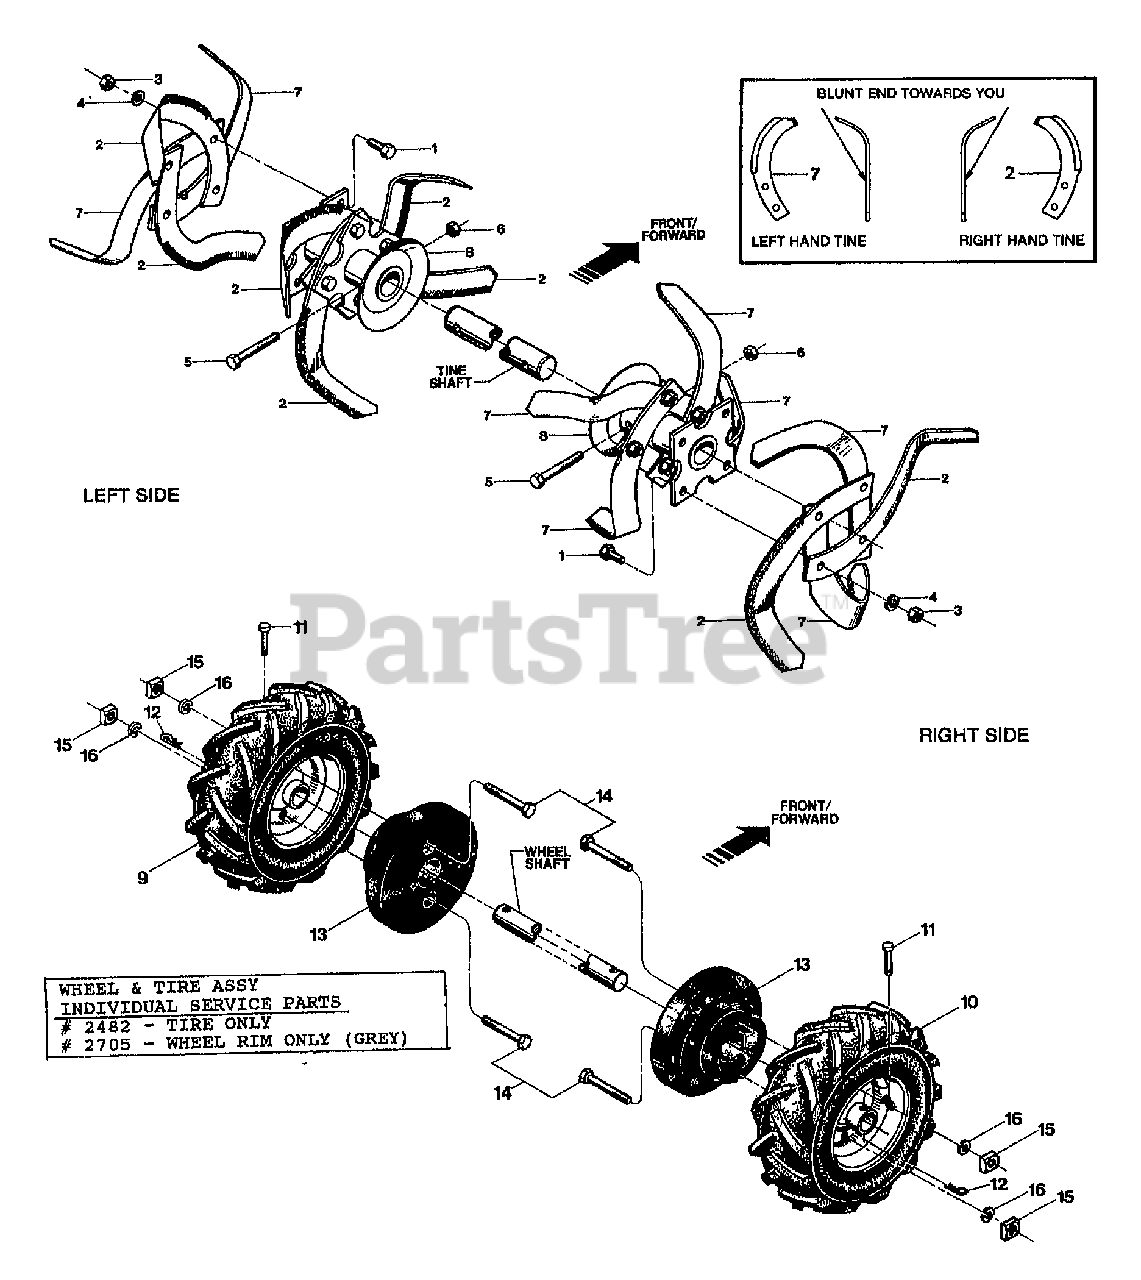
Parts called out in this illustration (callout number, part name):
1	SCR-HH 3/8-16X1.0 G5 ZP
2	TINE-BOLO RT W/HDW
3	NUT-HEX 3/8-16 ZP
4	WASHER-LK .375 @ DEPL
5	SCR-HH 3/8-16X2.00 G8 (HOLDER TO TILLER SHAFT)
6	NUT-H/LK 3/8-16
7	TINE-BOLO LT W/HDW
8	WELD-TINE HOLDER ECONO
9	ASSM-WHEEL TIRE LT (15-20 LBS AIR REQ'D)
10	ASSM-WHEEL TIRE RT (15-20 LBS AIR REQ'D)
11	PIN-CLEVIS
12	PIN-CLIP .08
13	WEIGHT-WHEEL
14	SCR-HH 3/8-16X3.5 G5 ZP
15	NUT-SQ 3/8-16
16	WASHER-LK .375 @ DEPL
